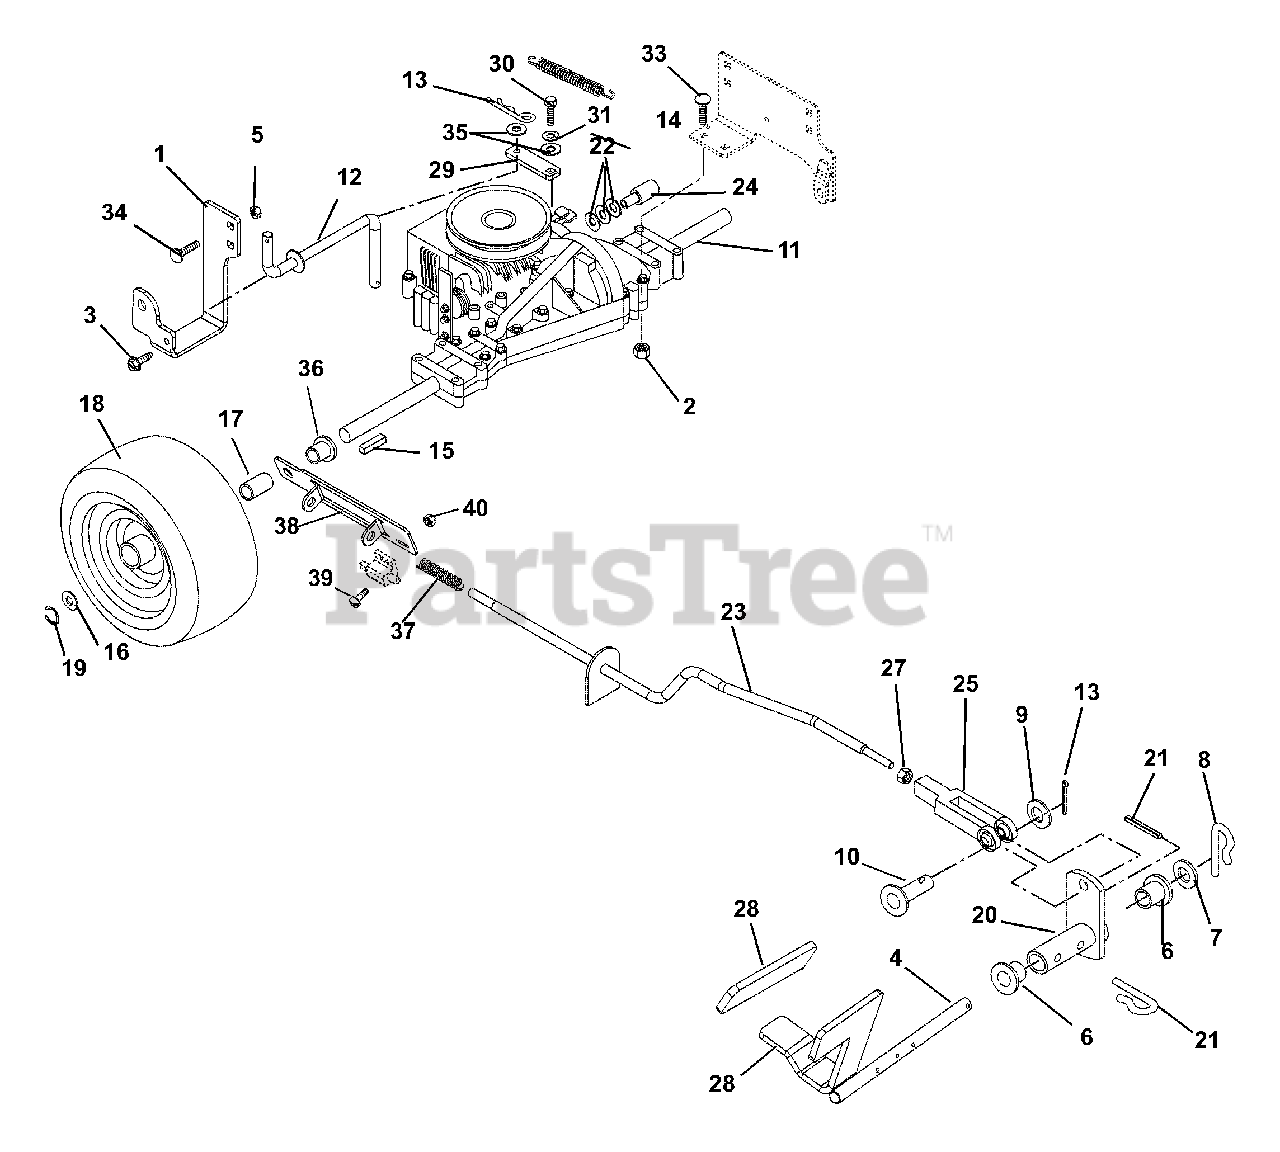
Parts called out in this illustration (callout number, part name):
1	SUPPORT, TRANS
2	NUT-FLG .50-13 PL
3	@SCR-TAP .31-18X.75 HWH TR YWZ
4	WELDM'T,NMIR SHIFT PEDAL
5	NUT-LK-TOP-FLG .38-16 BLKZC
6	BSHG-FLG .515X.750X.745X1.00NY
7	WSHR-FL-STL .505X1.00X.062YWZC
8	CLIP, SPRING
9	WSHR-FL-STL .328X.87X.179 YWZC
10	PIN-CLEV .312X.822 HDND PL
11	TRANS. PEERLESS LTH-2000-020
12	ROD, TRANS DISCONNECT
13	PIN-HAIR, ENDRIES #25 YWZC
14	SG-TENS .043X.44X3.31 WLD 5.8
15	KEY-SQ .188X2.0X.188 SAE 8630
16	WSHR-FL-STL .755X1.25X.125 YZ
17	SPACER WHEEL .75X1.0X1.25
18	ASSY-TIRE&WHEEL 16 X 6.5 X8
18	TIRE 16X6.50-8 2 PLY
19	RG-RTNG-EXT .750X.050
20	WLMDT-SHIFT ROD & HUB
21	@PIN-CTR .09X1.00 EXTPRSQCT YZ
22	WSHR-FL-STL .505X1.00X.062YWZC
23	ROD, NMIR SHIFT
24	TRUNNION
25	YOKE, .312-24 X 2.25
26	WSHR-FL-STL .390X.75X.125 YWZC
27	NUT-LK-NYL .375-24 W/INSR YWZC
28	GRIP, PEDAL
29	TAB, TRANS DISCONNECT
30	BLT-HEX .25-28X.75 GR5 YWZC
31	@WSHR-LK .25X.062 REG YWZC
32	WSHR-FL-STL .328X1.0X.094 YWZC
33	@BLT-RDHDSQNK .31-18X2.50 G5YZ
34	BLT-RDHDSQNK .38-16X.75 G5BZ
35	@WSHR-FL-STL.38X.875X.083 YWZC
36	BSHG-FLG .406X.88X.270X.140
37	SG-COMP .081X.720X2.75 PL
38	BRKT, NMIR SHIFT
39	@SCR-MCH 10-24X.75 HWH YWZC
40	@NUT-LK-NYL 10-24 W/INSRT YWZC
